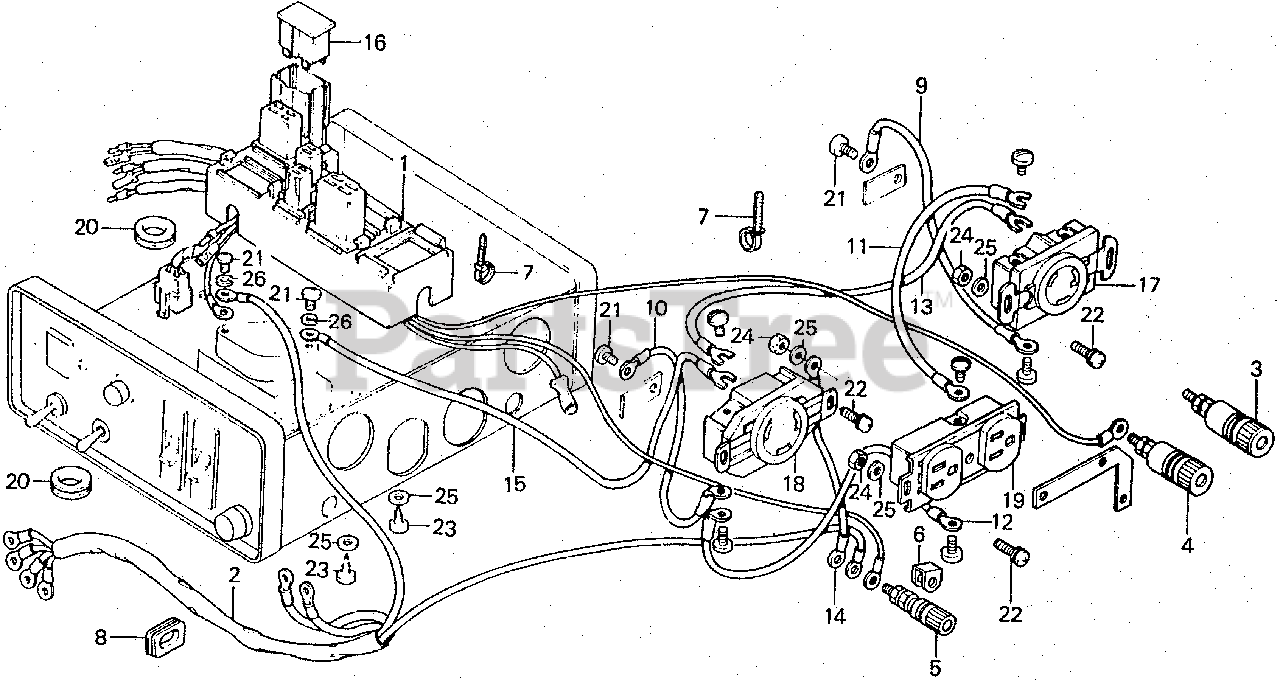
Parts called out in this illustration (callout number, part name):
1	WIRE HARNESS
2	WIRE, A.C. OUTLET
3	TERMINAL, D.C. OUT (+)
4	TERMINAL, D.C. OUT (-)
5	TERMINAL ASSY., GROUND (NOT AVAILABLE)
6	PLATE, GROUND
7	CLAMP, WIRE HARNESS
8	GROMMET, A.C. WIRE
9	WIRE, RECEPTACLE CIRCUIT BREAKER CONNECTING (200V)
10	WIRE, RECEPTACLE CIRCUIT BREAKER CONNECTING (100V)
11	WIRE, RECEPTACLE CONNECTING (100V-200V)
12	WIRE, RECEPTACLE CONNECTING
13	WIRE, RECEPTACLE CONNECTING (100V-200V)
14	WIRE, GROUND
15	WIRE, IDLE CONTROL UNIT CONNECTING (NOT AVAILABLE)
16	STACK ASSY., DIODE (2.7A)
17	RECEPTACLE (20A 250V) (NOT AVAILABLE)
18	RECEPTACLE (3-PRONG) (30A/125V)
19	RECEPTACLE (15A-125V)
20	GROMMET, WIRE HARNESS
21	SCREW, PAN (5X8)
22	SCREW-WASHER (4X12)
23	SCREW, TAPPING (4X12)
24	NUT, HEX. (4MM)
25	WASHER, PLAIN (4MM)
26	WASHER, SPRING (5MM)
